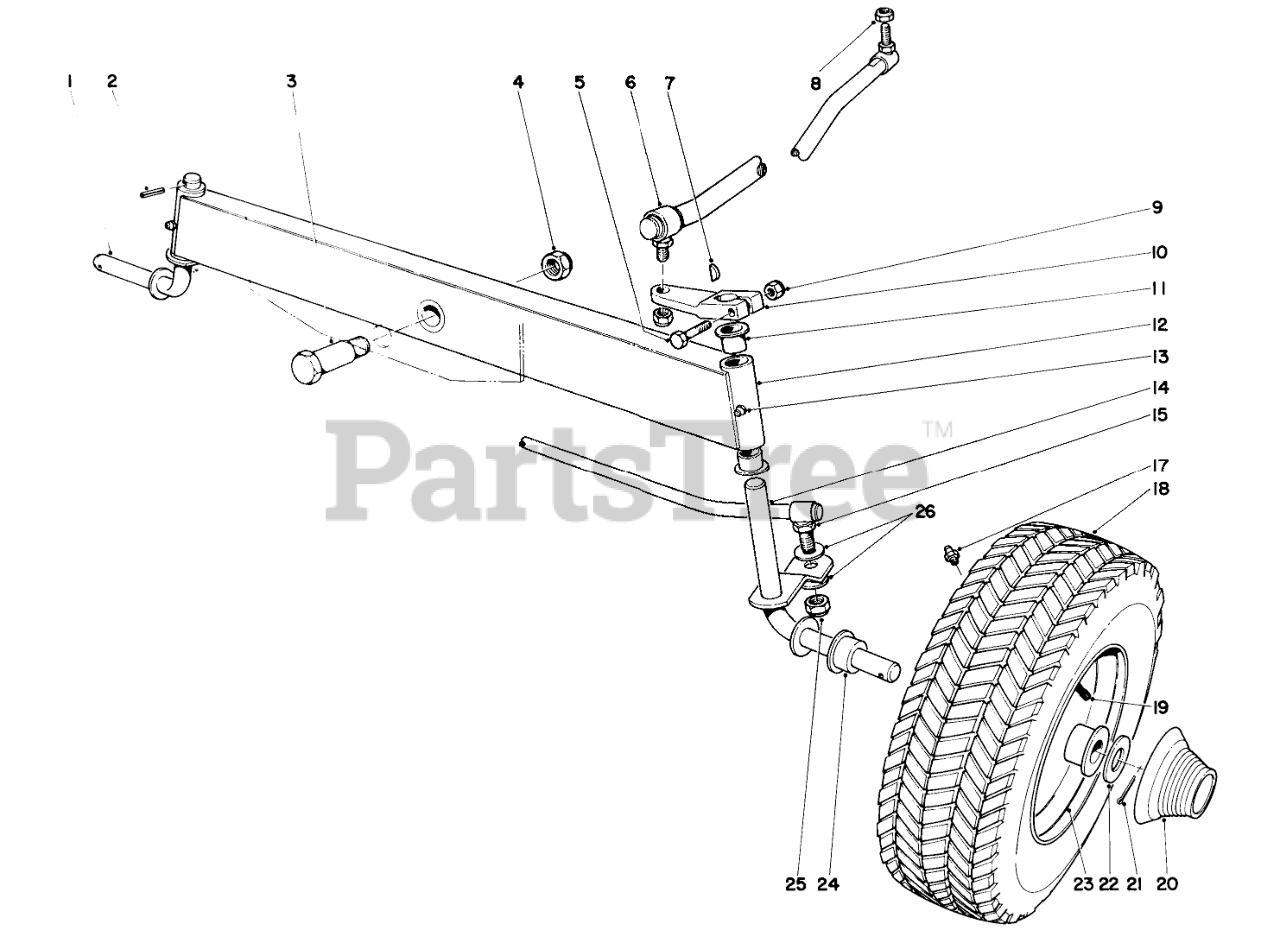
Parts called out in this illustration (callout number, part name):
1	Spindle
2	PIN-SPRING
3	Shoulder Bolt
5	SCREW-HH
6	Drag Link
7	KEY-WOODRUFF
8	Nut
10	Arm Drag Link
11	3/4IDX1LG FLANGE BSHG
12	Front Axle (Incl. Ref. #11)
13	Grease Fitting
14	Spindle
15	Tie Rod
17	FITTING-GREASE
19	Valve Stem
20	FRONT HUB CAP
21	PIN-COTTER
22	Washer
23	Rim
24	Bushing
25	Nut
26	Washer
